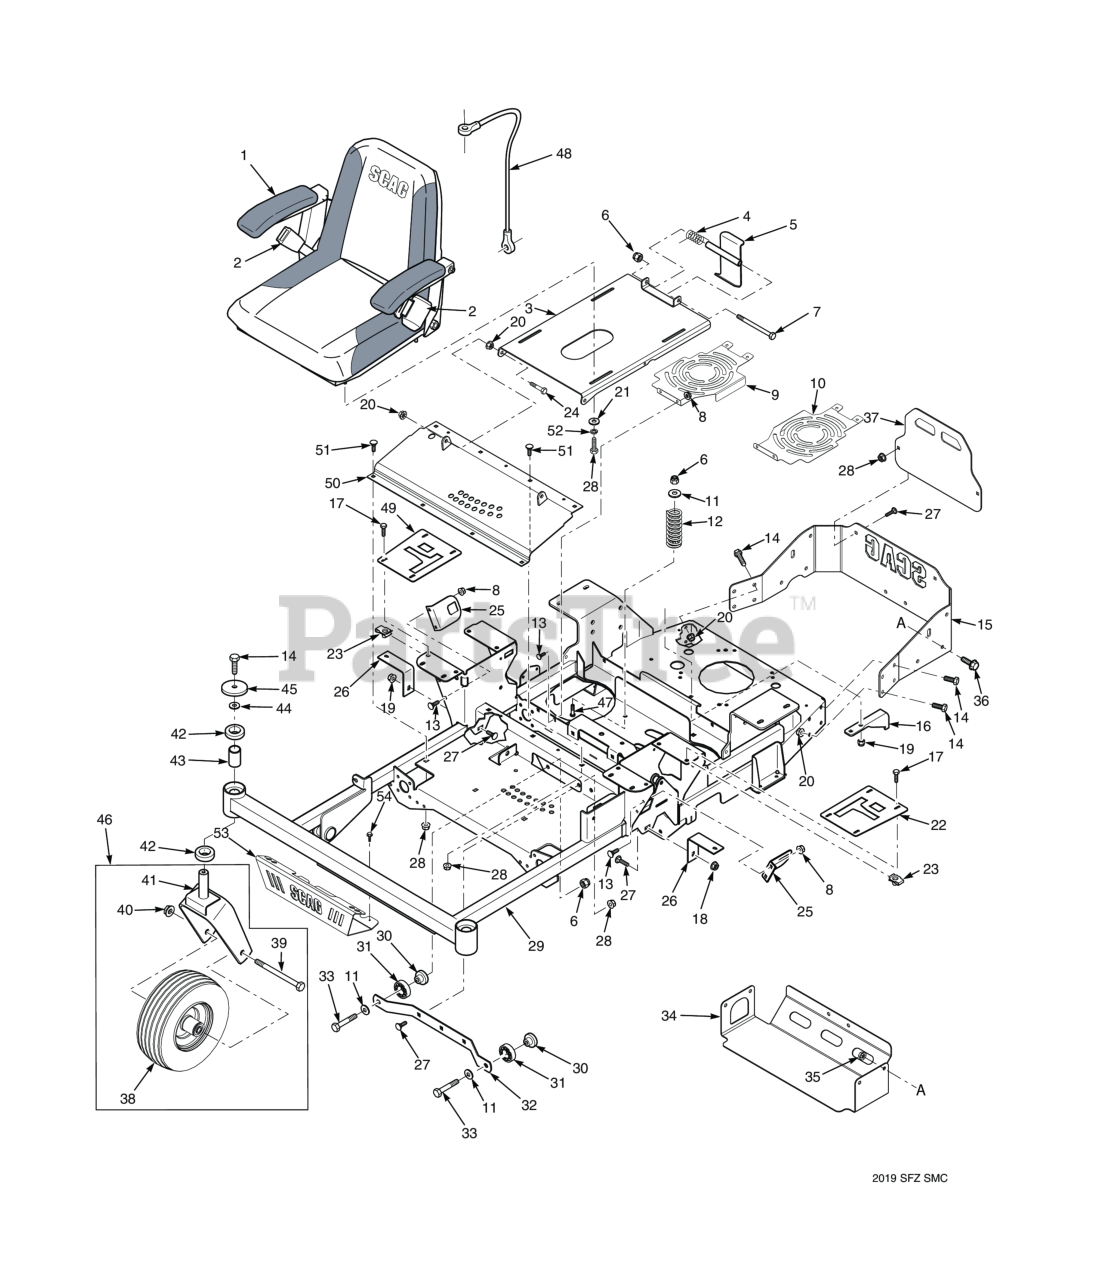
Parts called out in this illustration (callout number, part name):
1	Seat Assembly
1	Back Cushion
1	Cover, Bottom Cushion
1	Arm Rest Kit
1	Seat Pan
2	Seat Belt Assembly, Retractable
2	Hardware Package, Seat Belt Mounting
3	Seat Base w/Decal
4	Spring, Seat Latch
5	Weldment, Seat Latch
6	HEX NUT, ELASTIC STOP LOCK, 3/8-16
7	Bolt, 3/8-16 x 6.00" Hex Head
8	NUT, 1/4-20 SERRATED FLANGE HEX HEAD
9	Fan Cover, RH
10	Fan Cover, LH
11	Flatwasher, 3/8" Special (.391 x .938 x .105)
12	Spring, Seat
13	Bolt, Carriage 1/4-20 x 1/2"
14	Capscrew, 3/8-16 x 1.0" Serrated Flange Hex Hd
15	Rear Bumper
16	Bracket, Anti-Rotation
17	CAP SCREW, 1/4-20 X 1" SERRATED FLANGE HEX
18	Nut, Flange Head Elastic Stop 5/16-18
19	HEX NUT, ELASTIC STOP LOCK, 5/16-18
20	NUT, 3/8-16 SERRATED FLANGE HEX HEAD
21	Flatwasher, 5/16-.375 x .875 x .083 (35BV & 37BV-EFI)
22	Control Plate LH (Black)
23	Bolt, Hex Head 3/8-16 x 1"
24	Bolt, Hex Head, 3/8-16 x 1-1/2"
25	Bracket, Switch Mount
26	Bracket, Tank Mount
27	Bolt, 5/16-18 x .75 RHSN Carriage
28	BOLT, SERRATED FLANGE HEX HEAD 5/16-18 X 3/4"
29	Main Frame w/Decals
30	Spacer, Bearing
31	Bearing
32	Support, Deck Guide
33	Bolt, Hex Head 3/8-16 x 1-3/4" (Kohler EFI)
34	Heatshield
35	NUT, 3/8-16 SERRATED FLANGE HEX HEAD
36	Capscrew, 3/8-16 x 1.0" Serrated Flange Hex Hd
37	Guard, Engine, (Scag Gold)
38	Caster Wheel Assembly (INCL. Rim - 486311)
38	TIRE, 11 X 6.00-5
39	Bolt, Hex Head 1/2-13 x 7-1/2" (48"/52")
40	HEX LOCKNUT, ELASTIC STOP, 1/2-13
41	Yoke, Caster Wheel
42	Bearing
42	Spacer, Yoke
43	Spacer, Caster Bearing
44	Flatwasher, 7/16" (.500 x 1.25 x .083")
45	Flatwasher, 3/8-.406 x 2.25" x .1875
46	Caster Wheel Assembly w/Yoke
47	SHORT SQ. NECK CARRIAGE BOLT, 3/8-16 X 1-1/4"
48	Cable, Seat Stop
49	Control Plate RH (Black)
50	Weldment, Deck Lift Cover w/Decal
51	Carriage Bolt, 5/16-18 x 1/2"
52	Lockwasher, 5/16 (.317 x .586 x .078) Helical Spring
53	Bumper. Front
54	Screw, 1/4-20 x .375"
